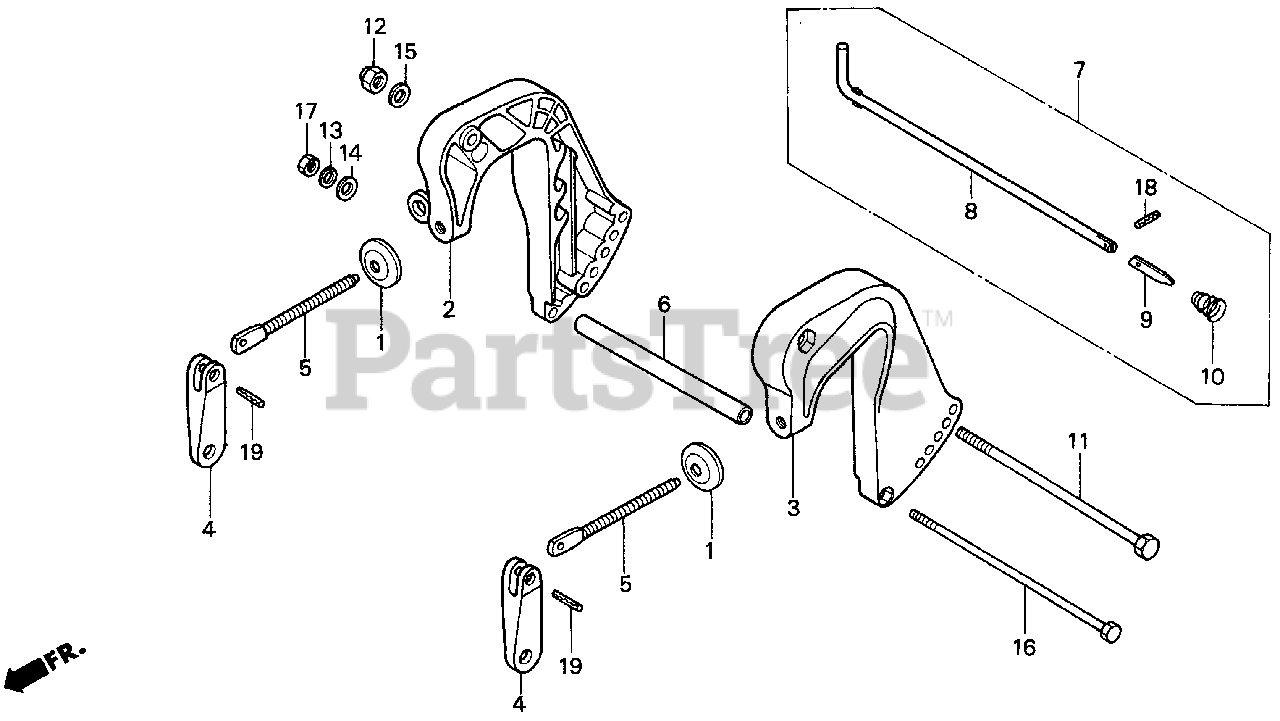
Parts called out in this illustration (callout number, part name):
1	PLATE, PUSH
2	BRACKET, R. STERN *NH282MU* (OYSTER SILVER METALLIC-U)
3	BRACKET, L. STERN *NH282MU* (OYSTER SILVER METALLIC-U)
4	GRIP, CLAMP
5	SCREW, CLAMP
6	COLLAR, DISTANCE (6MM)
7	ROD, ADJUSTING
8	ROD, ADJUSTING
9	STOPPER, ROD
10	SPRING, ROD ADJUSTING
11	BOLT, HEX. (8X130)
12	NUT, SELF-LOCK (8MM)
13	WASHER, SPRING (6MM)
14	WASHER, PLAIN (6MM)
15	WASHER (8MM)
16	BOLT, HEX. (6X140)
17	NUT, HEX. (6MM)
18	PIN, SPRING (2X6)
19	PIN, SPRING (4X22)
